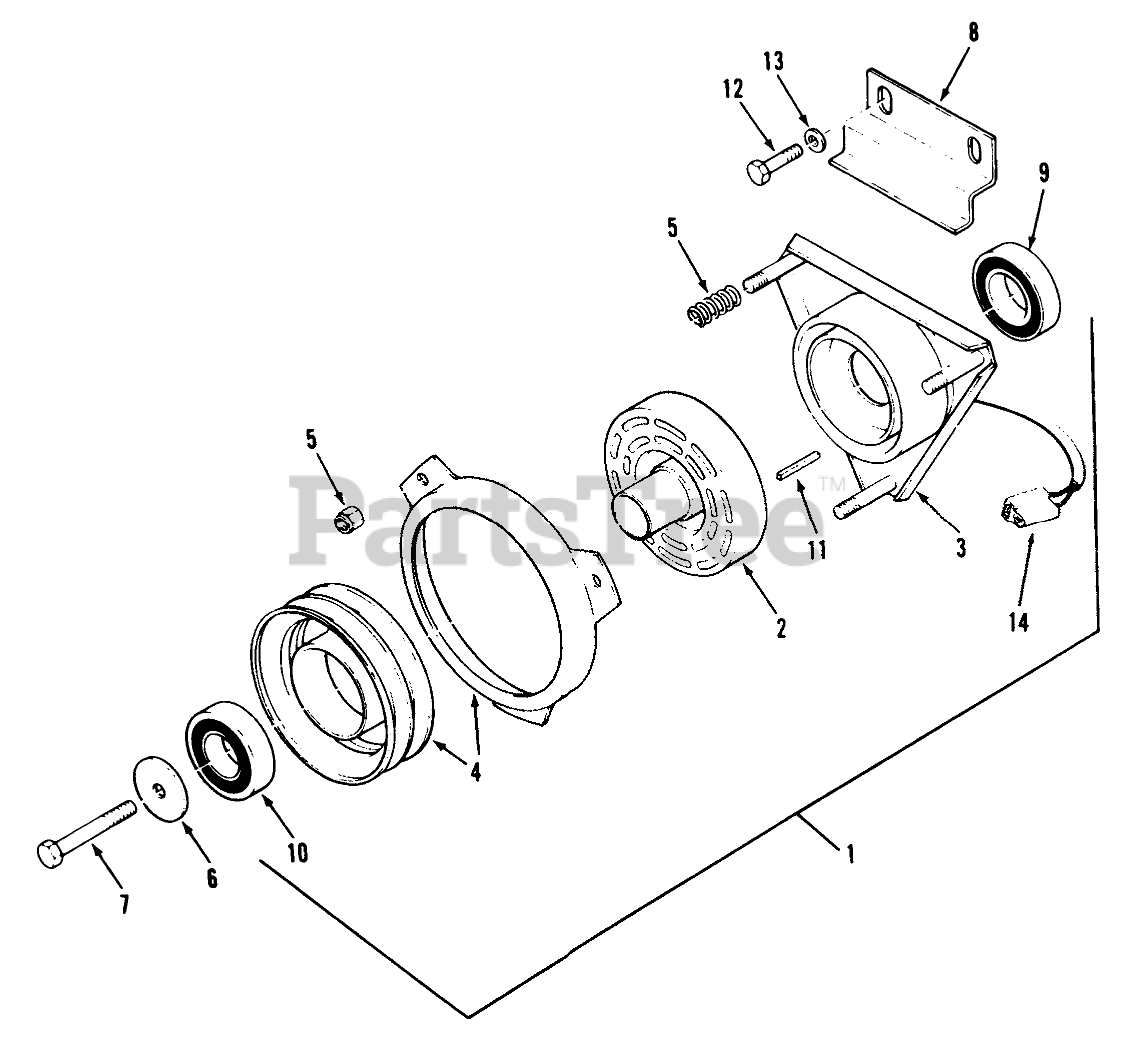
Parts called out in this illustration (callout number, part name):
1	Electric Clutch-Complete (Incl. Ref.s #2, 3, 4, 5, 9, 10, & 14)
2	Rotor
3	Field (Incl. Ref. #9)
4	Armature & Pulley (Incl. Ref. #10)
5	ACCESS SPRING & NUT
6	RETAINER-BEARING
7	SCREW-HH
8	BRACKET-CLUTCH B
9	BEARING-FIELD ASS'Y
10	BEARING-ELEC CLUTCH
11	KEY-SQUARE
12	SCREW-HH
13	WASHER-FLAT
14	CONNECTOR BODY B
